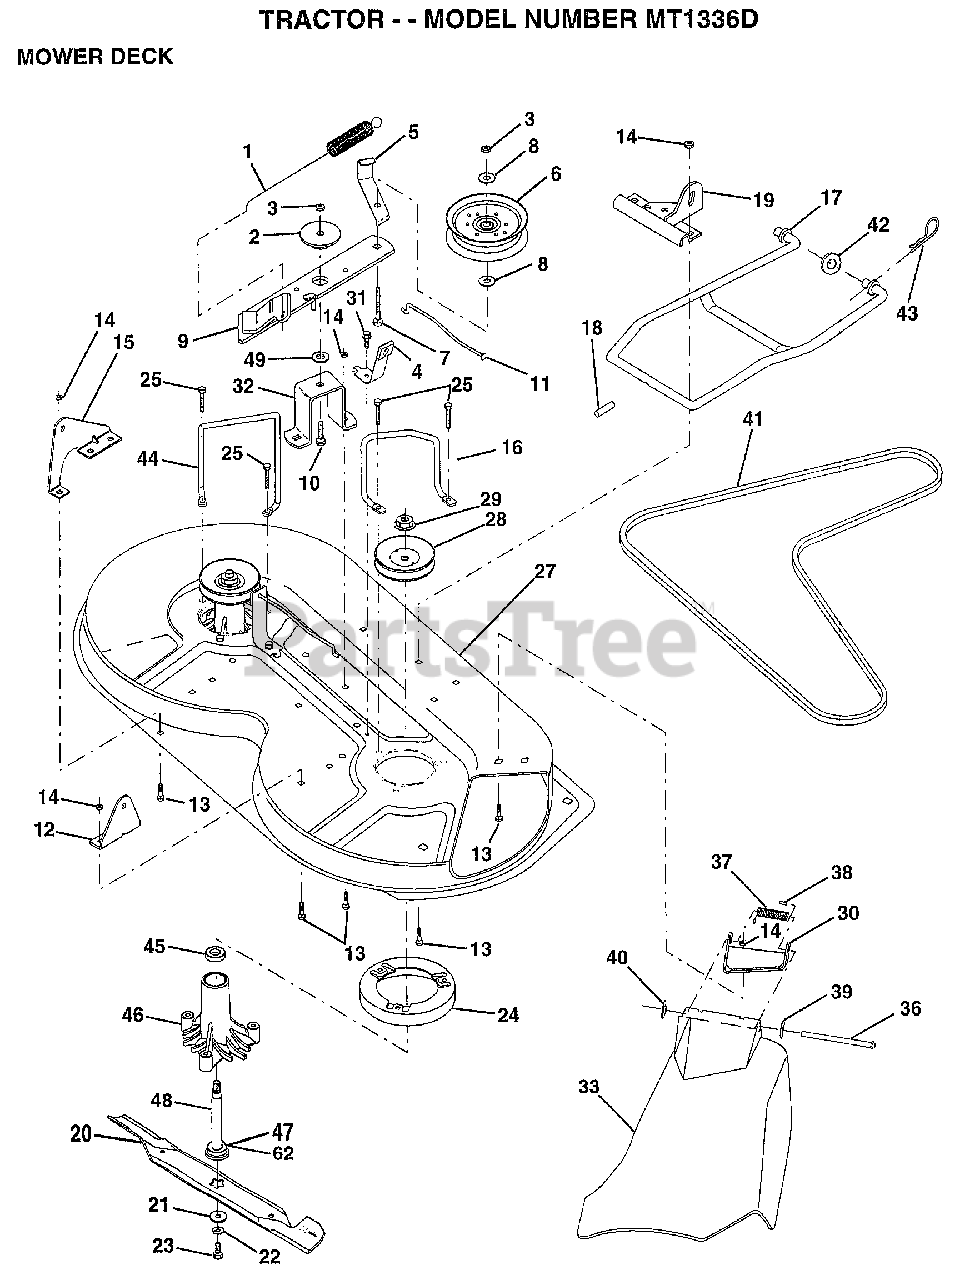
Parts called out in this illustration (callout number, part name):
1	SPRING CLUTCH MWR
2	SPACER RETAINER
4	BRAKE ASM
5	IDLER BELT GUIDE
6	PULLEY IDLER
7	BOLT
8	WASHER
10	BOLT.3/8-14X1.25
11	BRAKE ROD
12	"BRKT,LIFT REAR"
13	BOLT
15	"BRKT,LIFT REAR LH"
16	"KEEPER-BELT,RH"
17	MOWER LINK STAB
18	"PIN,GROOVE"
19	"BRKT,LINK STABILI"
20	"BLADE.36"" HIPERF"
21	WASHER.HARD.BLADE
23	BLADE BOLT
24	STRIPPER RND MWR
25	"SCREW-THD ROLL,WA"
27	"HOUSING-MOWER,36"""
28	PULLEY.MAND.36/46
31	SCREW LT
32	"SUPT,IDLER ARM"
36	HINGE ROD
37	SPRING TORSION
38	CAP-SLEEVE LT
39	WASHER
40	NUT PUSH M
41	V-BELT.PRIM.78.5.
43	RETAINER.SPRING
44	KEEPER BELT LH
45	BEARING
46	HSG ASM MANDREL
47	BEARING.BALL
49	HARDENED WASHER
62	WASHER.FELT.
